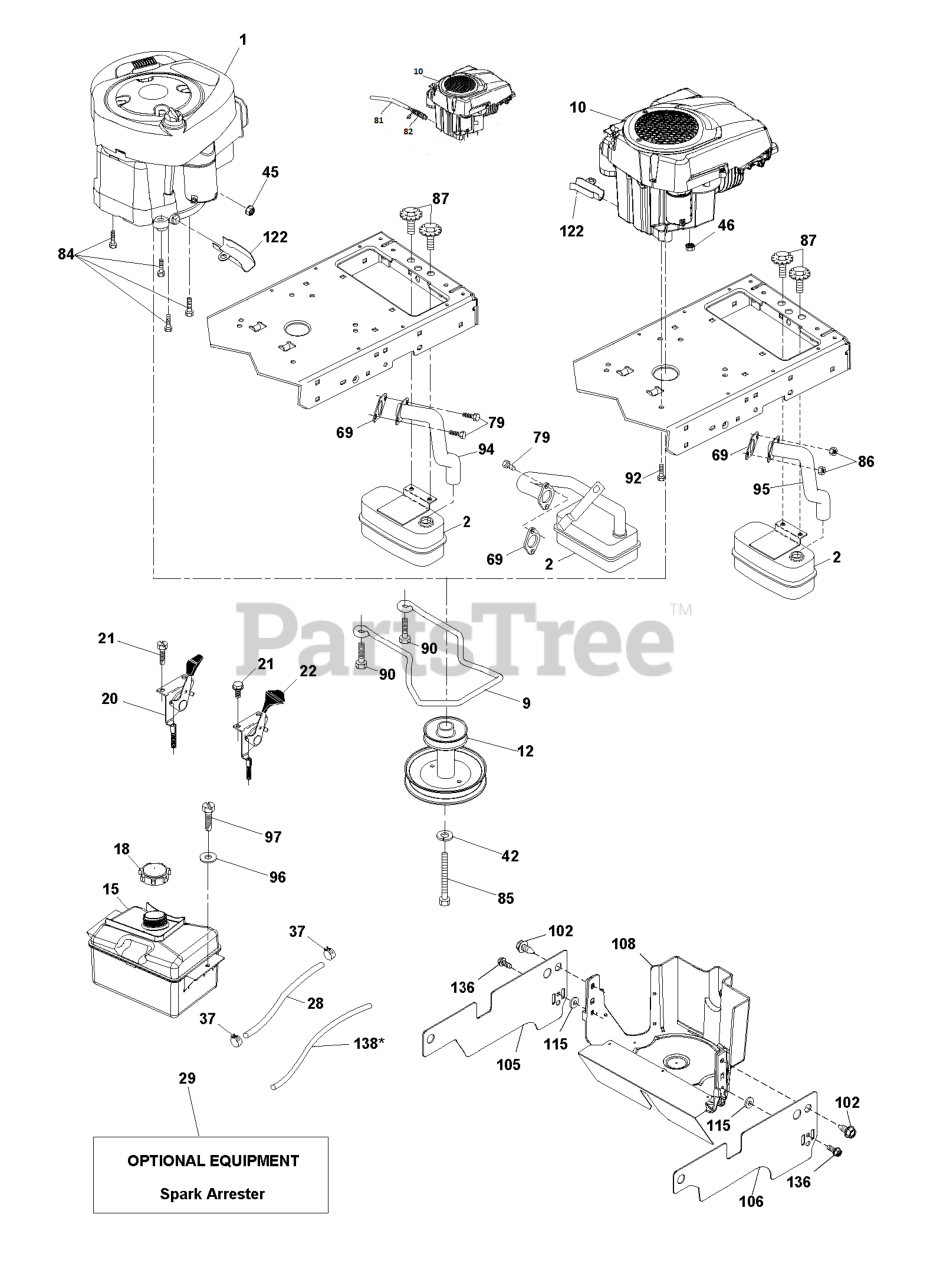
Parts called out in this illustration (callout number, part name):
2	MUFFLER.SINGLE.CYL.KOHL/B&S
2	MUFFLER.ASM.SINGLE
2	MUFFLER.LT.BRIGGS.14HP.IC/OHV
9	KEEPER.BELT.ENG.3.25"2BOLT.PNT
9	Keepers
10	ENGINE.LONCIN.SPARE/452
10	ENGINES
12	ENGINE.PULLEY
12	PULLEY.ENGINE
15	FUEL TANK
15	FUEL.TANK.ASM.NON-EPA
18	CAP.2.25'.VENTED.RATCHET.EPA
20	THROTTLE CABLE
22	CONTROL.TH/CK.C.BLACK
28	HOSE.1/4".LOW.PERM.FUEL.LN.22"
28	HOSE 1/4" LOW PERMEATION FUEL
29	KIT.SPARK ARRESTOR 794945 B&S
37	HOSE CLAMP
45	Hardware
46	NUT HEXAGON WITH FLANGE, SERRA
69	GASKET GASKET.EXHAUST.LONCIN 3
69	GASKET.ENG.1.313 ID.TIN PLATED
79	Screws
81	TUBE, DRAIN OIL ASM.
82	VALUE.OIL.DRAIN
84	SCREW.3/8-16
85	BOLT.HEX.7/16-20X4.GR5.1.5BLUE
86	NUT.HEX.FLANGE.TOPLOCK
87	BOLT.5/16-18UNCX3/4 W/SEMS.BLK
90	SCREW 3/8-16X1
92	SCREW 3/8-16X1
94	EXHAUST.TUBE.B&S.28/31
95	TUBE TUBE.EXHAUST.LONCIN 452.T
95	TUBE TUBE.EXHAUST.LONCIN 608.T
97	SCREW HEXWSHR 1/4-20X3/4
102	BOLT.HEX.HD.WASHER.5/16-18X.75
105	SHIELD.SIDE.LH.3842"TEX FRN.BK
106	SHIELD.SIDE.LH.3842"TEX FRN.BK
108	COVER ENGINE PULLEY COVER WITH
115	RETAINER
122	EXTENSION DRAIN OIL
